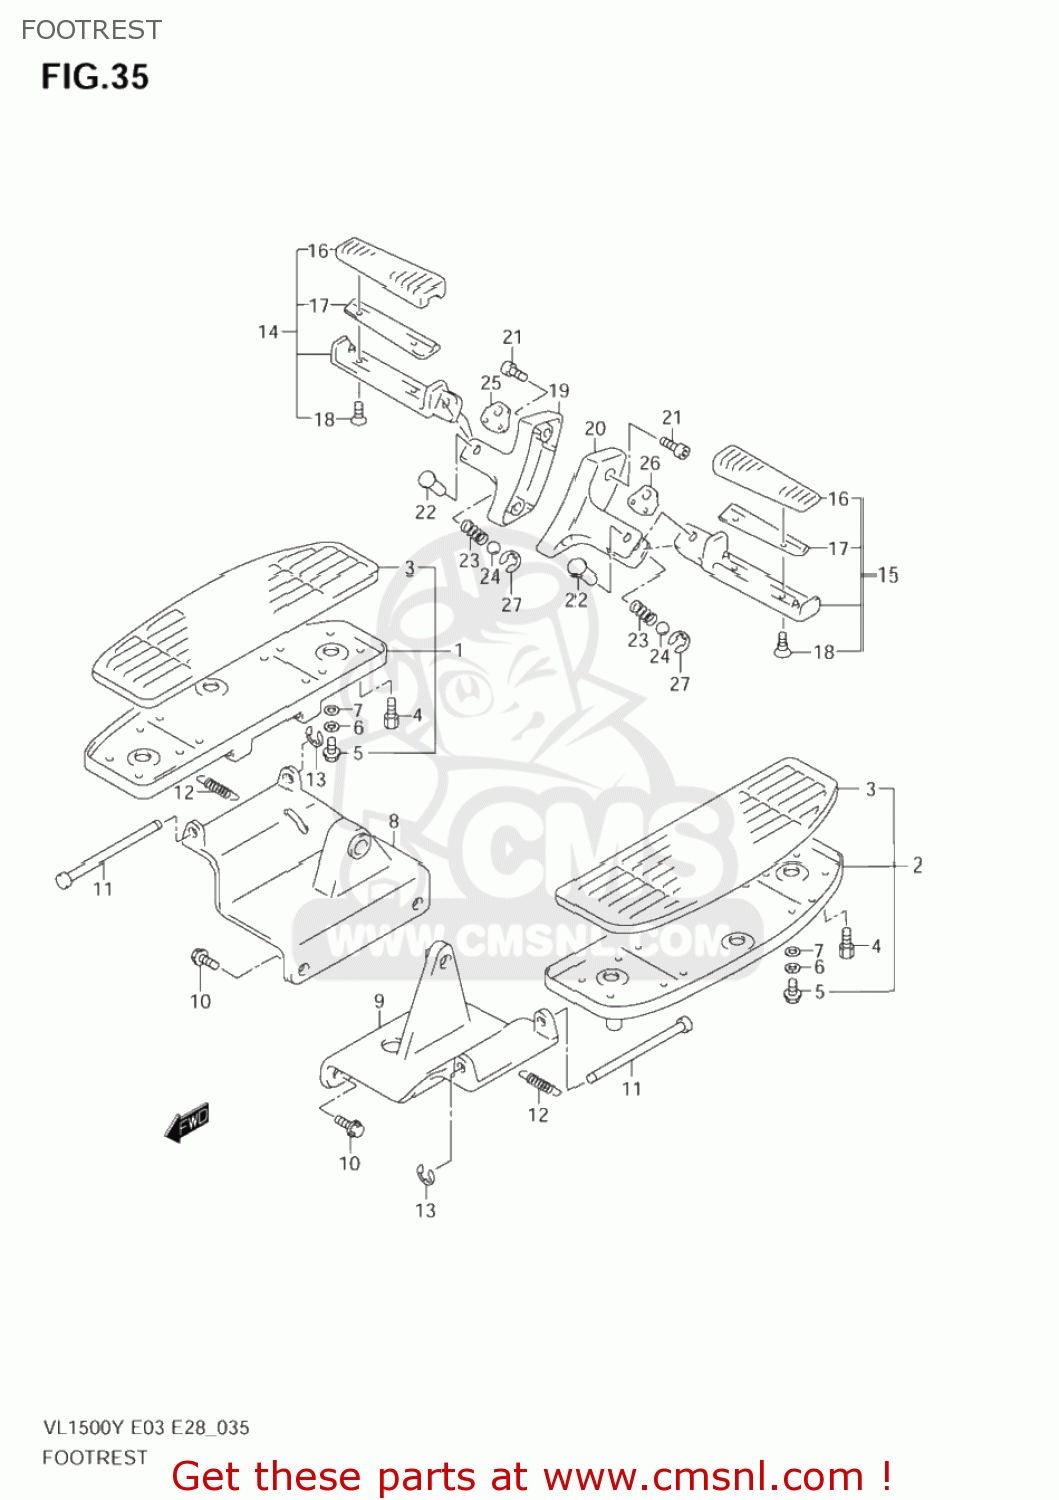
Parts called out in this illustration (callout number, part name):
1	FOOTREST ASSY,FR,R
2	FOOTREST ASSY,FR,L
3	RUBBER,FR FOOTREST
4	BOLT,BANK SENSOR
5	BOLT
6	WASHER (6.5X22X1.6)
7	CUSHION
8	BRACKET,FR FOOTREST,R
9	BRACKET,FR FOOTREST,L
10	BOLT
11	PIN,FR FOOTREST
12	SPRING
13	E.RING
14	FOOTREST ASSY,PILLION,R
15	FOOTREST ASSY,PILLION,L
16	RUBBER,PILLION FOOTREST
17	PLATE,RUBBER STOPPER
18	SCREW(5X16)
19	BRACKET,PILLION FOOTREST
20	BRACKET,PILLION FOOTREST
21	BOLT
22	PIN
23	SPRING
24	BALL
25	PLATE,PILLION FOOTREST,R
26	PLATE,PILLION FOOTREST,L
27	E.RING
